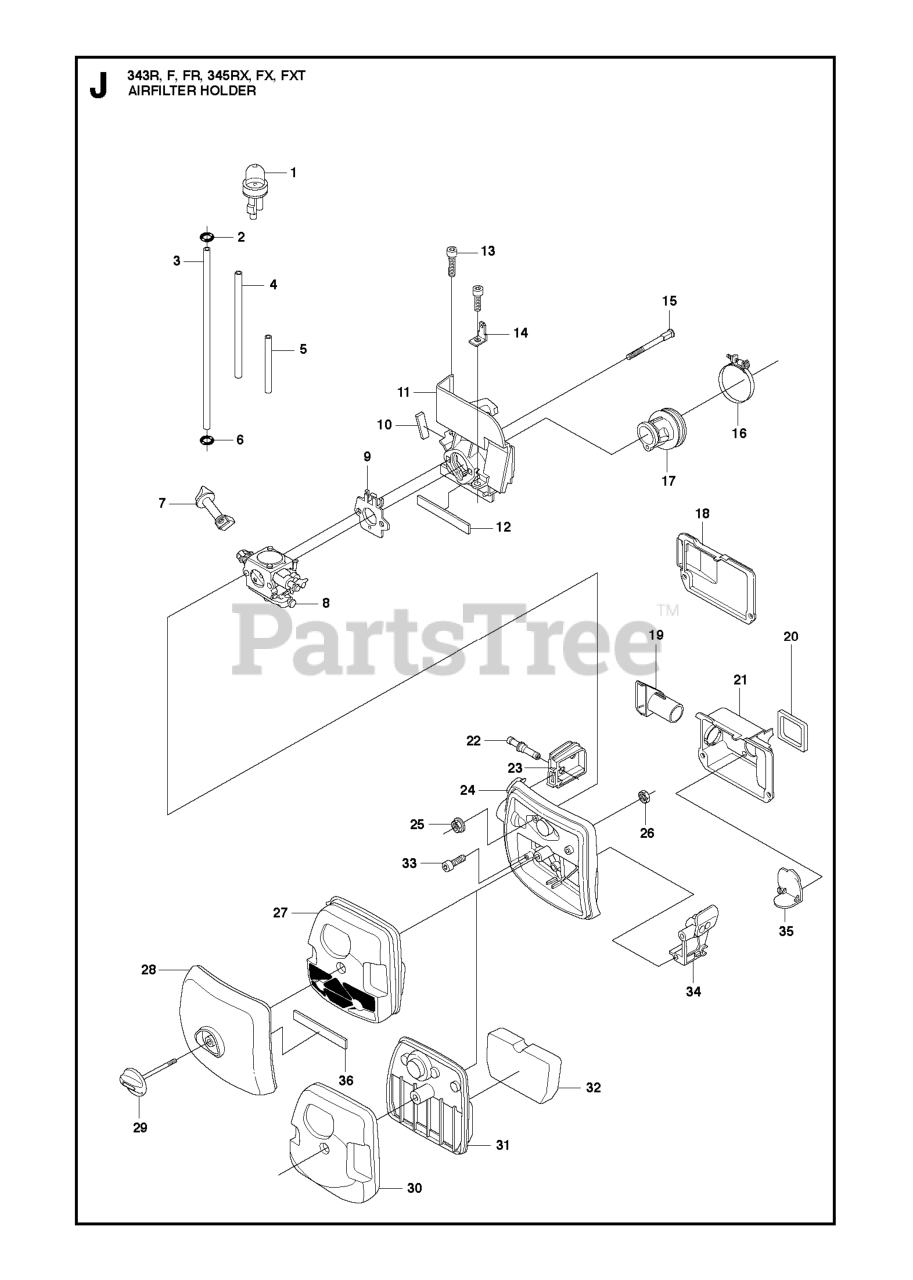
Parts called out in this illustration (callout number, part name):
1	AIR PURGE BUBBLE
3	FUEL HOSE
4	HOSE.FUEL L=102
5	NOSE
7	CHOKE CONTROL
8	CARBURETOR
9	SPACER WASHER
16	CLAMP
18	COVER
19	AIR CONDUCTOR
20	SEAL
21	AIR CAN
24	FILTER HOLDER
26	NUT M6M M5
27	AIR FILTER
28	RP FILTER COVER COMP
29	HANDLE AIR FILTER COVER
30	COVER
31	BASE
32	AIR FILTER
34	SCREW DRIVER GUIDE
35	COVER
